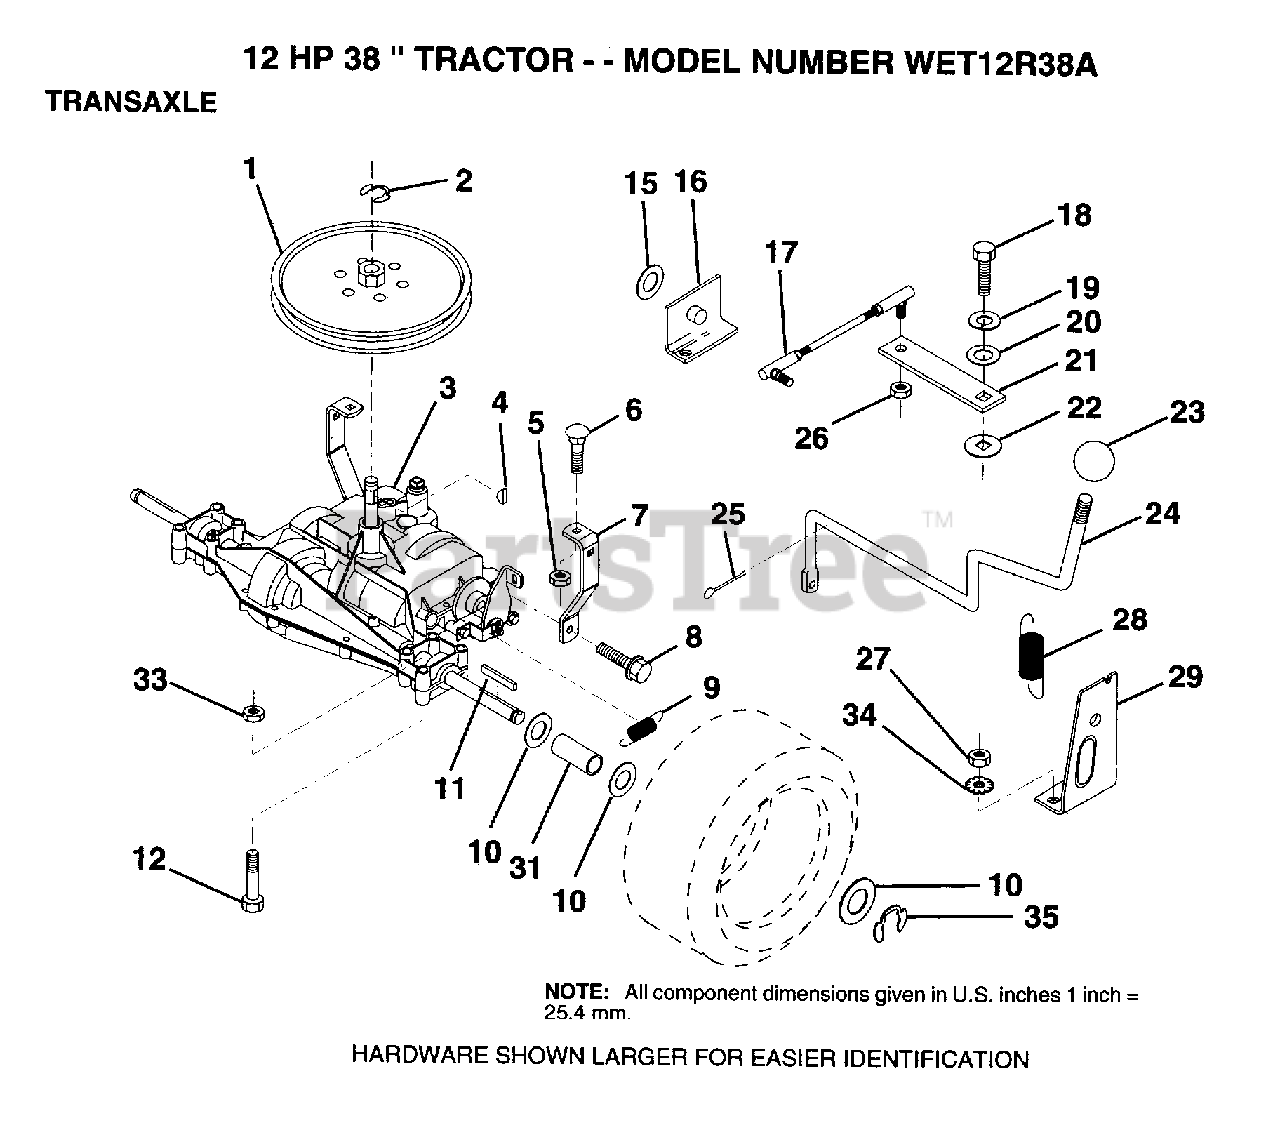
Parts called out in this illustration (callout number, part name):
1	PULLEY
3	TRANSAXLE.6SP.D
6	BOLT
7	"STRAP,TORQUE"
8	SCREW
10	WASHER
11	SQUARE KEY
12	BOLT
16	"SUPT,HDLE SHT LH"
17	"LINK,SHIFT"
19	LOCKWASHER
20	WASHER LT
21	"ARM,SHIFT"
22	WASH-SHFT PLT LT
23	KNOB T (1/2-HOLE)
24	"ROD,SHIFT"
25	PIN COTTER 1/8
26	NUT.LOCK.5/16-24
28	"SPRING,EXT"
31	SPACER
34	LOCKWASHER.5/16.E
35	E-RING LT
